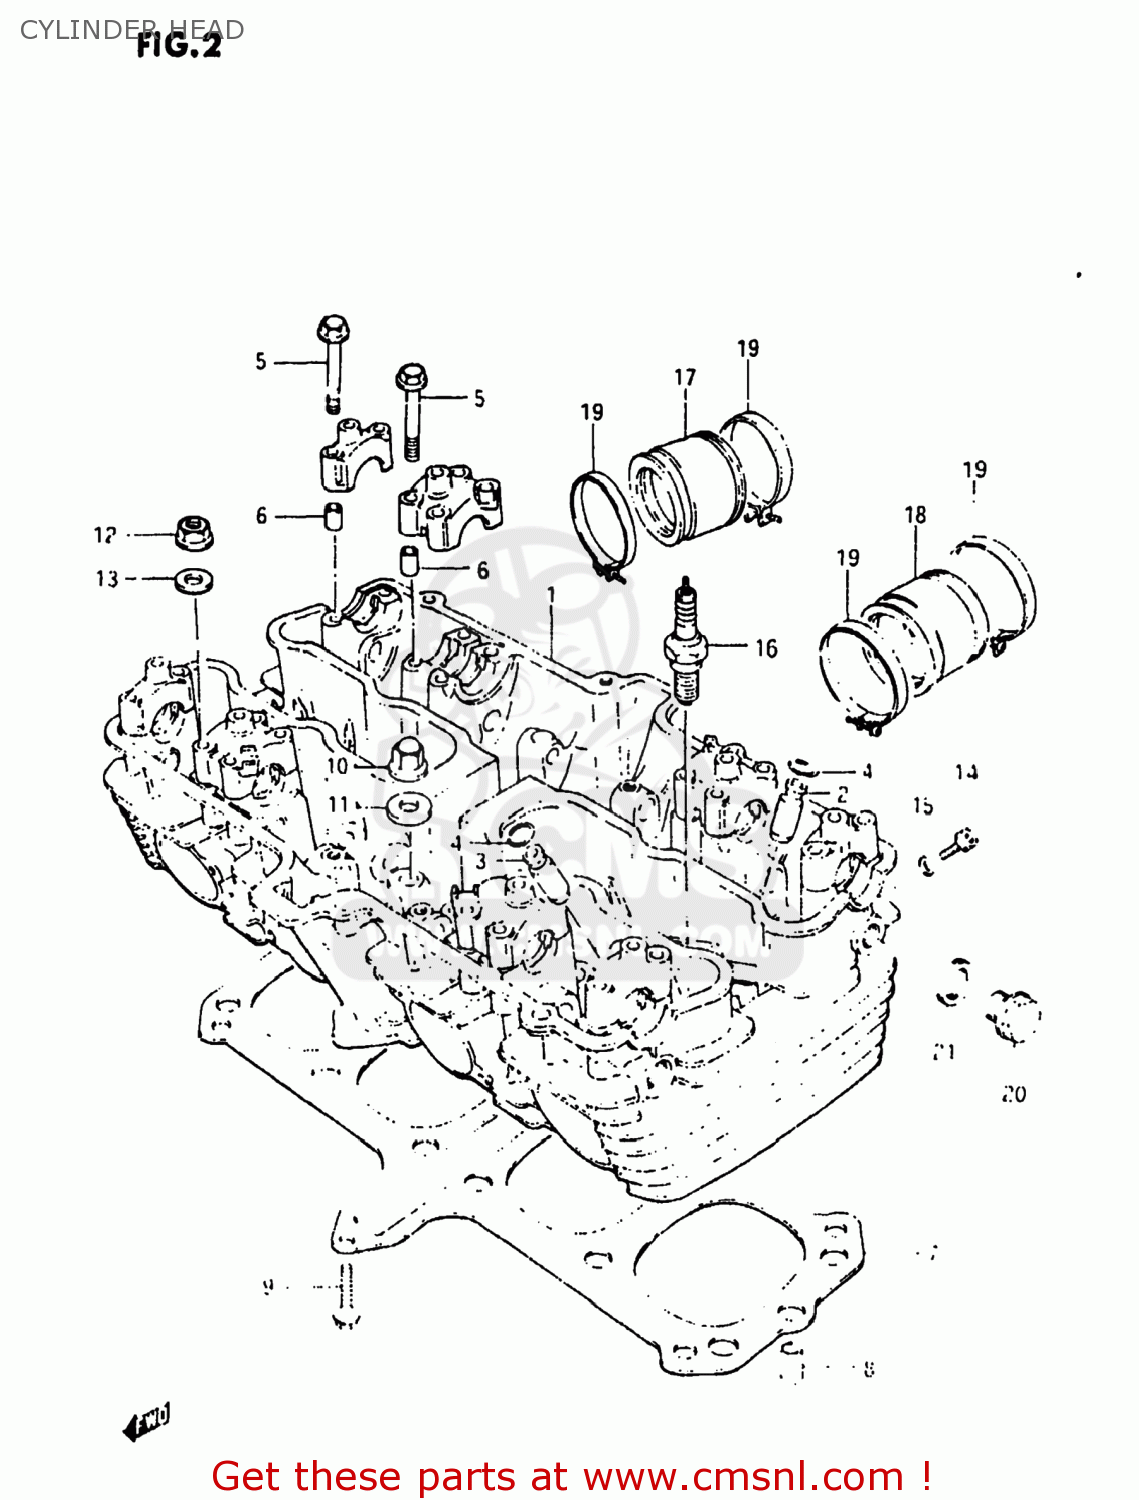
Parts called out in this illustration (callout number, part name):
1	HEAD,CYLINDER (16 VALVE)
2	GUIDE,INTAKE VALVE
3	GUIDE,INTAKE VALVE
4	RING,SNAP
5	BOLT(6X39)
6	PIN(6.2X8X11)
7	GASKET,CYLINDER HEAD (NAS)
8	PIN
9	BOLT 6X30
10	NUT
11	GASKET(10.5X22X2) (NAS)
12	NUT
13	WASHER(10.5X22X2.3)
14	BOLT, INTAKE PORT
15	GASKET(5.3X9.3X1.2) (NAS)
16	SPARK PLUG D9EA
17	PIPE,INTAKE RH
18	PIPE INTAKE (NAS)
19	CLAMP
20	PLUG (14X12)
21	GASKET(14X19.2X2) (NAS)
